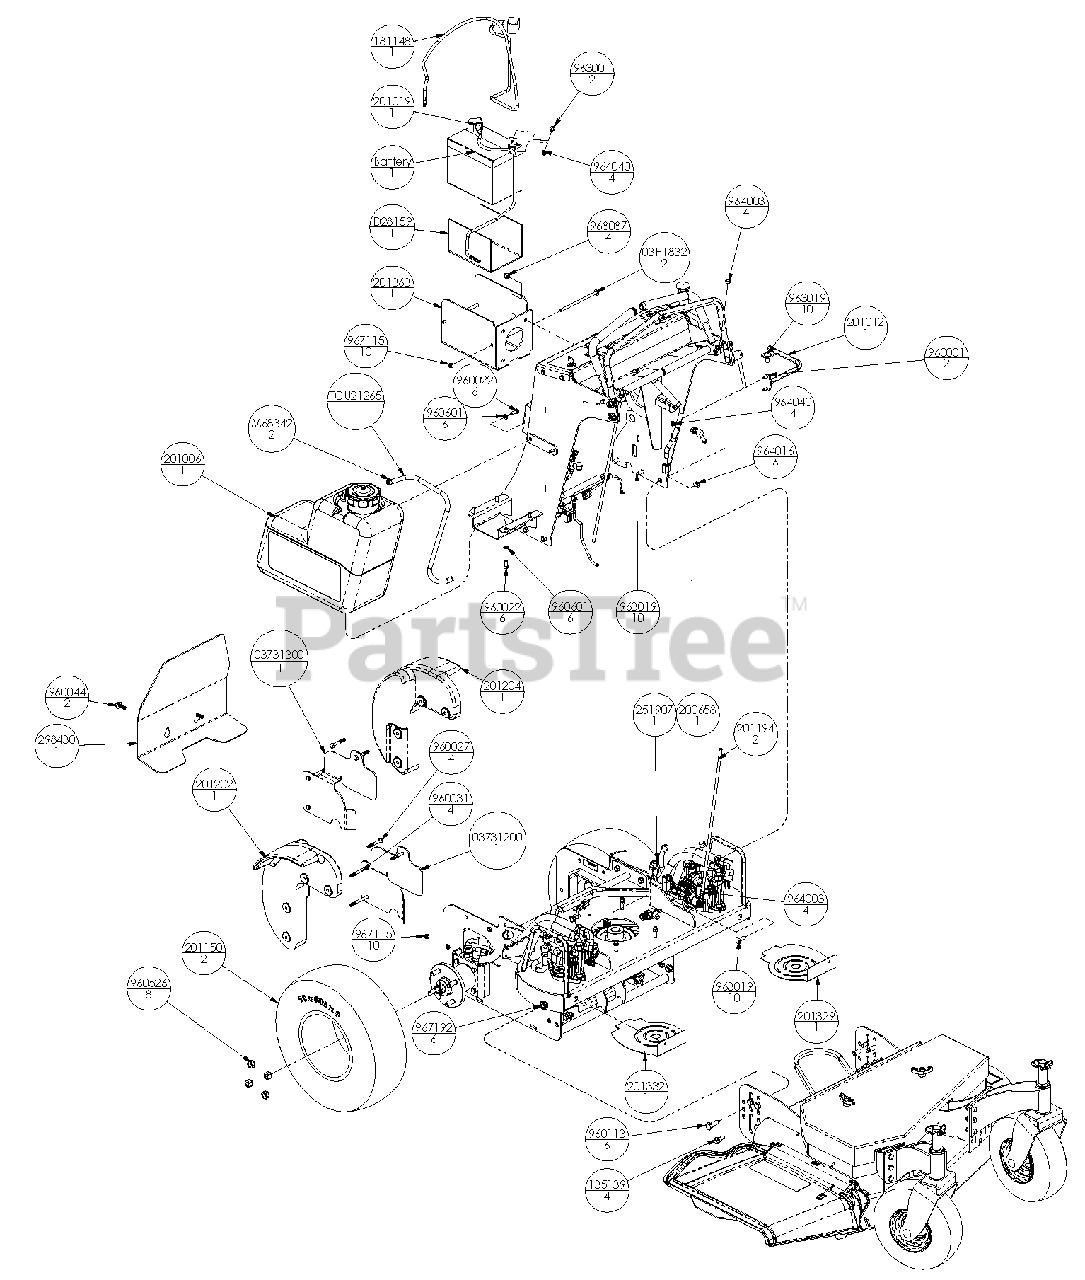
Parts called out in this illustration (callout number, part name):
1	STRIP, BATTERY INSULATOR
2	CLAMP, HOSE (RED) #
3	HOSE, 1/4" ID LOW PERM FUEL 50
4	BOLT, 5/16-18 X 6.00 CRG 2 Y
5	BOLT, 1/2 X 1.06 X 3/8-16 SLD 5 Y
6	CABLE, BATTERY STARTER - 48"
7	BATTERY, 12V-U1-CCA270MIN
8	PIN, CVS SPG 3/8" YOKE SPEC Y
9	TANK, FUEL SCORPION ASSEMBLY
10	WLDT, RESERVIOR GUARD
11	CABLE, BATTERY - 25" GROUND
12	CONSOLE BATTERY BRACKET
13	SHIELD, LH PUMP
14	SHIELD, RH PUMP
15	SHIELD, RH MOTOR
16	SHIELD, LH MOTOR
17	ASSY, TIRE/WHL 18/6.5X8 SLVR
18	SHIELD, ENGINE
19	ROD, CONTROL 5/16 X 22.75 Y
20	RH CAST WEIGHT MACHINED
21	LH CAST WEIGHT MACHINED
22	YOKE, 3/8-24 RH ADJUSTABLE
23	BOLT, 1/4-20 X .750 HEX 5 Y
24	BOLT, 5/16-18 X .750 HEX 5 Y
25	BOLT, 5/16-18 X 2.00 HEX 5 Y
26	BOLT, 5/16-18 X 3.00 HEX 5 Y
27	BOLT, 3/8-16 X 1.00 FGH 8 Y
28	BOLT, 1/2-13 X 1.25 HEX 5 Y
29	NUT, 1/2-20 LUG C
30	WASHER, .313 MED SPRG LOCK Y
31	BOLT, 1/4-20 X .625 WSH Y
32	BOLT, 3/8-16 X 1.00 CRG 5 SN Y
33	NUT, 5/16-24 STD HEX GR5 Y
34	LOCKNUT, 3/8-16 WHIZ Y
35	LOCKNUT, 1/4-20 WHIZ Y
36	LOCKNUT, 5/16-18 NYLOC Y
37	LOCKNUT, 1/2-13 WHIZ GR5 Y
38	LOCKNUT, 3/8-16 NYLOC Y
